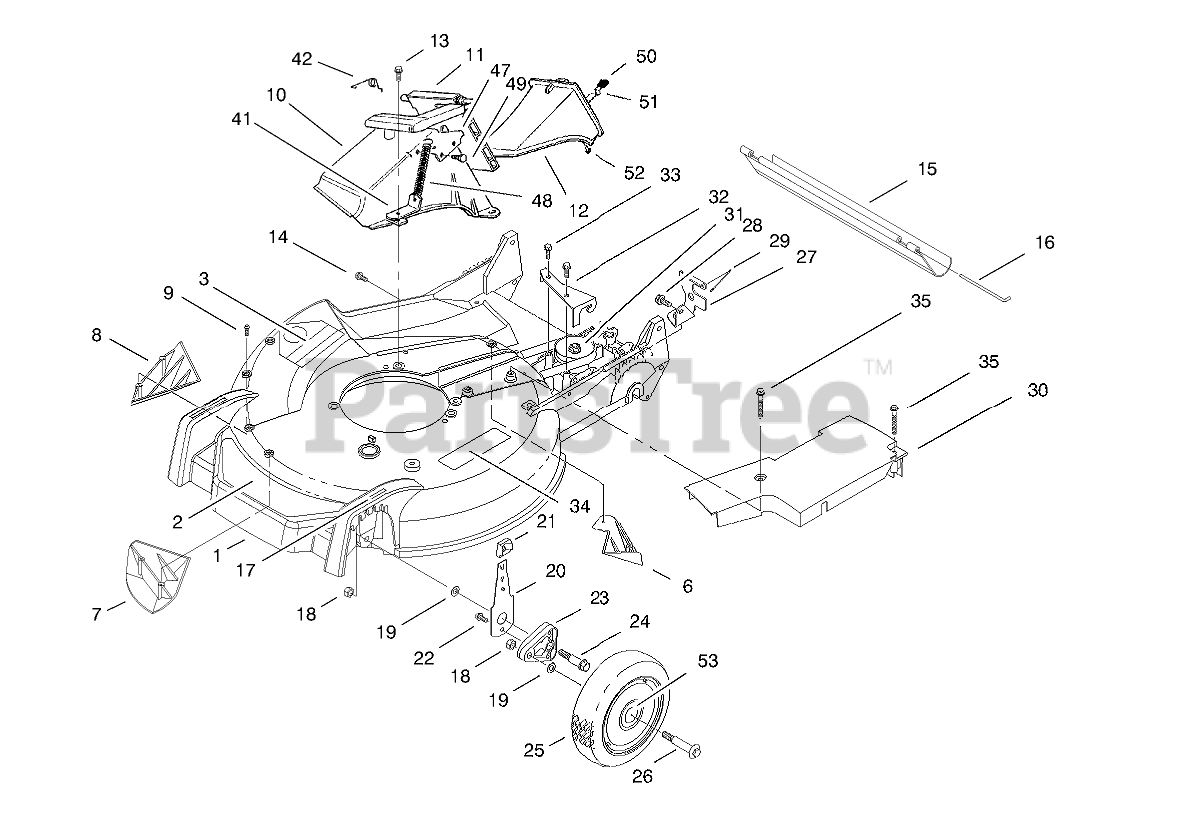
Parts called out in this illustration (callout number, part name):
1	Housing-Rwd (Incl. Ref. #3, 6-9, 17, & 34)
2	DECAL - DECK
3	DECAL-DANGER
6	KICKER-REAR
7	KICKER-FRONT
8	KICKER-RH
9	SCREW-PPH
10	TUNNEL-DISCHARGE
11	DISCHARGE DOOR ASM
12	DISCHARGE PLUG ASM
13	SCREW-HWH
14	SCREW AND WASHER ASM
15	SHIELD-TRAILING
16	ROD-SHIELD
17	DECAL - HOC
18	NUT-LOCK
19	WASHER
20	FRONT SPRING ARM ASM
21	KNOB-ARM
22	SCREW-HWH
23	ARM-PIVOT, FRONT
24	BOLT-SHOULDER
25	ASM-Wheel & Tire (Incl. Ref. #53)
26	BOLT-WHEEL
27	Bracket-Adj. Trac
28	SCREW-HWHTF
29	RETAINER-CABLE
30	COVER - BELT
31	GEARCASE ASM
32	Bracket-Guide
33	SCREW-HWHTF
34	DECAL-WARNING
35	SCREW-HHFTF
41	BRACKET-SPRING
42	RETAINER-DOOR
47	LATCH-PLATE
48	SPRING-DOOR
49	SCREW-PLASTITE
50	GRIP-LATCH
51	LATCH-PLUG, DISCHARGE
52	RIVET-HEAD, FLAT
53	BUSHING
